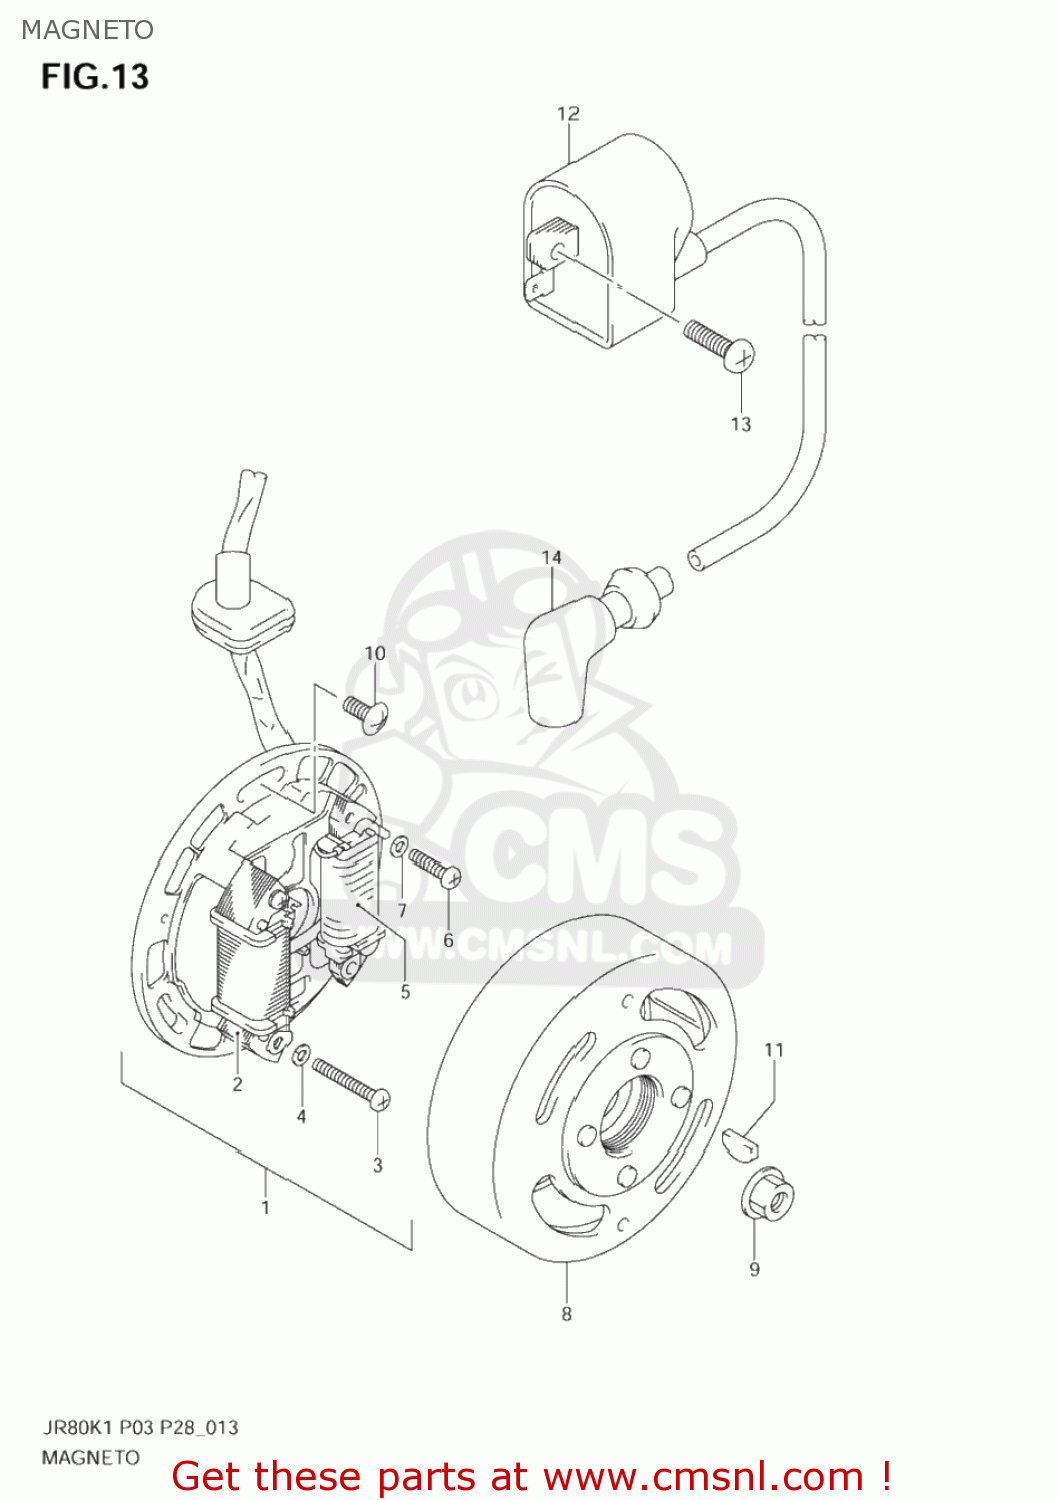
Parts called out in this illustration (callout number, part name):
1	STARTER ASSY
2	COIL,LIGHTING
3	SCREW
4	WASHER,LOCK
5	COIL,PRIMARY
6	SCREW 4X16
7	WASHER,LOCK
8	ROTOR ASSY
9	NUT
10	SCREW 5X12
11	KEY
12	UNIT & COIL ASSY,IGNITION
13	SCREW, 6X20
14	CAP,SPARK PLUG
